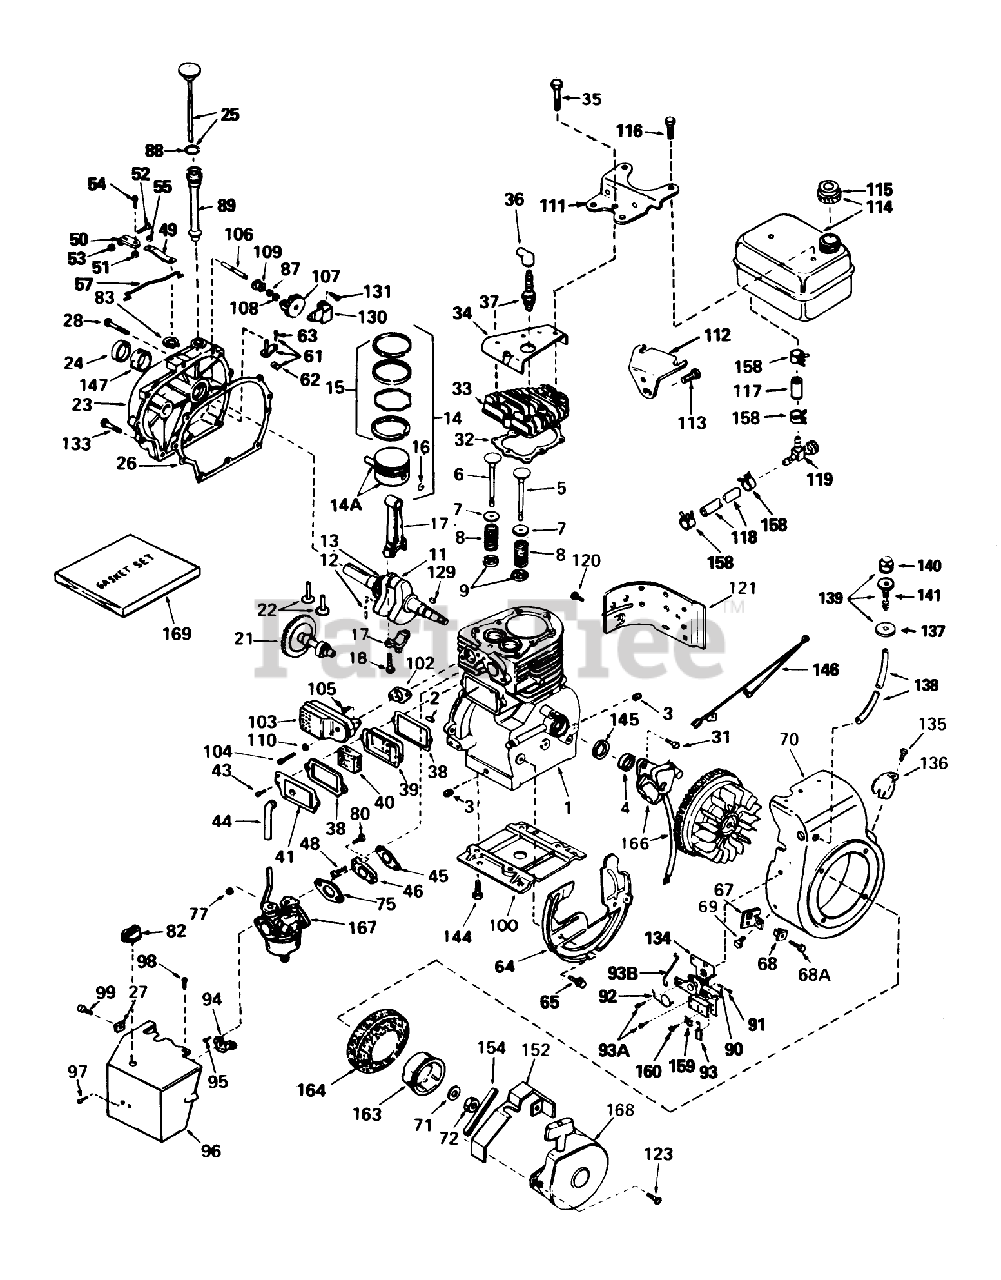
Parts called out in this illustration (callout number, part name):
1	Cylinder Assy. (Incl. Nos. 2, 3 4)
2	Pin-Dowel
3	Plug-Drain, Oil (SQH 1/4-18)
4	Seal, Oil
5	Valve, Intake (Standard)(Incl. No. 9)
5	Valve, Intake (1/32" oversize)(Incl. No. 9)
6	Valve, Exhaust (Standard)(Incl. No. 9)
6	Valve, Exhaust (1/32" oversize)(Incl. No. 9)
7	Cap-Spring, Valve
8	Spring-Valve
9	Keeper-Spring, Valve
11	Crankshaft Assy. (Incl. Nos. 12 13)
12	Pin, Groove
13	Gear-Crankshaft
14	Piston, Pin Ring Assy. (Std.)(Incl. Ref. #14A, 15 16)
14	Piston, Pin Ring Assy. (.010 Oversize)(Incl. Ref. #14A, 15 16)
14	Piston, Pin Ring Assy. (.020 Oversize)(Incl. Ref. #14A,15 16)
14A	Piston Pin Assy. (Std.)(Incl. Ref. #16)
14A	Piston Pin Assy. (.010 Oversize)(Incl. Ref. #16)
14A	Piston Pin Assy. (.020 Oversize)(Incl. Ref. #16)
15	Ring Set, Piston (Std.)
15	Ring Set, Piston (.010 Oversize)
15	Ring Set, Piston (.020 oversize)
17	Rod Assy., Connecting (Incl. Ref. #18)
18	Bolt, Connecting Rod
21	Camshaft, BCR
22	Lifter-Valve
23	Cover, Cylinder (Incl. Nos. 24 106)
24	Oil Seal
25	A Dipstick, Oil (Incl. Ref. #88)
26	Gasket-Cover, Cylinder
27	Nut-U Type
28	Screw (1/4-20 x 1-1/4)
31	Screw
32	Gasket-Head, Cylinder
33	CYLINDER HEAD
34	Cover-Head, Cylinder
35	Screw (5/16-18 X 2-1/2)
36	Cover-Spark Plug
37	Plug, Spark (J17LM or equiv.)
37	Plug, Spark (Champion RCJ-8)
38	Gasket-Breather
39	Body-Breather
40	Element-Breather
41	Cover-Valve
43	Screw
44	Tube-Breather
45	Gasket-Intake
46	Flange, Carburetor (Incl. Nos. 77 80)
48	Screw
49	Lever-Governor
50	Clamp-Lever, Governor
51	Nut-Lock
52	Screw
53	Nut-Lock
54	Screw
55	Washer-Lock
57	Governor Link
61	Rod, Governor (Incl. Nos.62 63)
62	Yoke-Governor
63	Screw (6-40x5/16)
64	Baffle Blower Housing
65	Screw (1/4-20x19/32)
67	Bracket
68	Grommet
68A	Screw
69	Screw, Hex Hd.
70	Housing, Blower (Incl. Ref. #135 136)
71	Washer
75	Gasket-Carburetor
77	Nut and Lock Washer (1/4-28)
80	Screw
82	Knob-Control
83	Ring-Retaining
87	Washer-Flat
88	O-Ring
89	Tube Fill
90	Spring-Compression
91	Screw
92	Spring-Throttle
93	Terminal
93A	Screw (10-32 x 1/2)
93B	Link-Throttle
94	Bracket-Choke
95	Screw (10-32 x 1/2)
96	Cover, Carburetor
97	Screw (8-32 X 5/16)
98	Screw (10-32x1/2)
99	Screw (8-32 x 3/8)
100	Base Engine
102	Gasket Exhaust
103	Muffler
104	Screw (5/16-18 X 2)
105	Screw
106	Shaft-Governor
107	Governor Gear ASM
108	Ring-Retaining
109	Spool, Governor
110	Washer
111	Plate, Fuel Tank Mounting
112	Bracket, Fuel Tank-Lower
113	Screw (1/4-20x19/32)
114	53023/VAR.10/16HP O
115	Cap, Fuel
116	Screw (1/4-15x7/8)
117	Line-Fuel
118	Line-Fuel (8.62)
119	Valve-Shut Off
120	Screw
121	Emnsion, Blower Housing
123	Screw
129	Key, Flywheel
130	Bracket, Governor
131	Screw (10-32 x 35/64)
133	Screw
134	Control Assy., Remote Speed (Incl. Ref. #90 thru 93)
135	Screw (8-32 x 3/8)
136	Screw
137	Retainer, Primer Bulb
138	Line, Primer
139	Primer Assy. (Incl. Nos. 89, 90 91)
140	Bulb, Primer
141	Body, Primer
144	Screw
145	Gasket Stator
146	Wire, Ground
147	Bushing-Crankshaft
152	Guard-Starter
154	Seal, Snowguard
158	Clamp-Line, Fuel
159	Conduit
160	Screw (10-32 x 3/8)
163	Cup-Starter
164	Screen, Air
166	Magneto
167	Carburetor (Incl. Ref. #75)
168	Starter Assy., Rewind
169	Gasket Set (Incl. Items Marked *)
